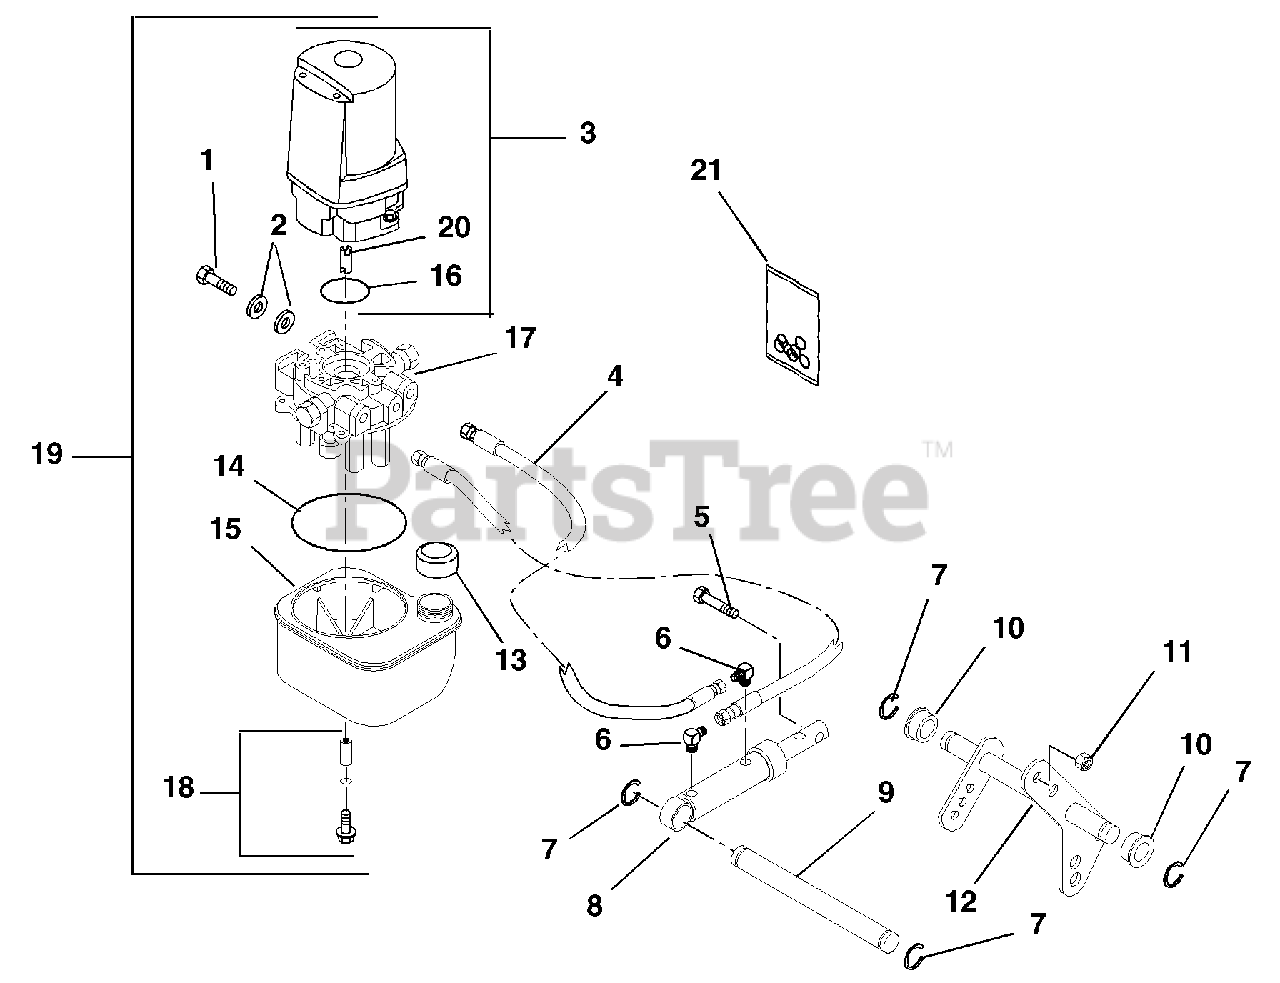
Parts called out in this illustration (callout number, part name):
1	Bolt-Hex .38-16 x 1.00 Grade 5
2	Washer-Flat-Steel .39 x .88 x .18
3	Assembly, Motor
4	Assembly, Hose Pump To Cylinder
5	Bolt-Hex .50-13 x 2.00 Grade 5
6	Adapter
7	Ring-Retaining-External .84 x .056
8	Cylinder, Hydraulic
9	Shaft, Hydraulic Cylinder
10	Bushing-Flange 1.02 x 1.39 x .75 x 1.75 Nylon
11	Nut-Locking-Center .50-13
12	Weldment, Mower Lift
13	Reservior Cap-Electric/Hydraulic Pump
14	Reservior Tank
15	Reservior Seal, O-Ring
17	Adapter Assembly
18	Screw, O-Ring and Spacer Assembly
19	Pump, Electric Hydraulic
21	Seal/O-Ring Kit, Electric/Hydraulic Pump
